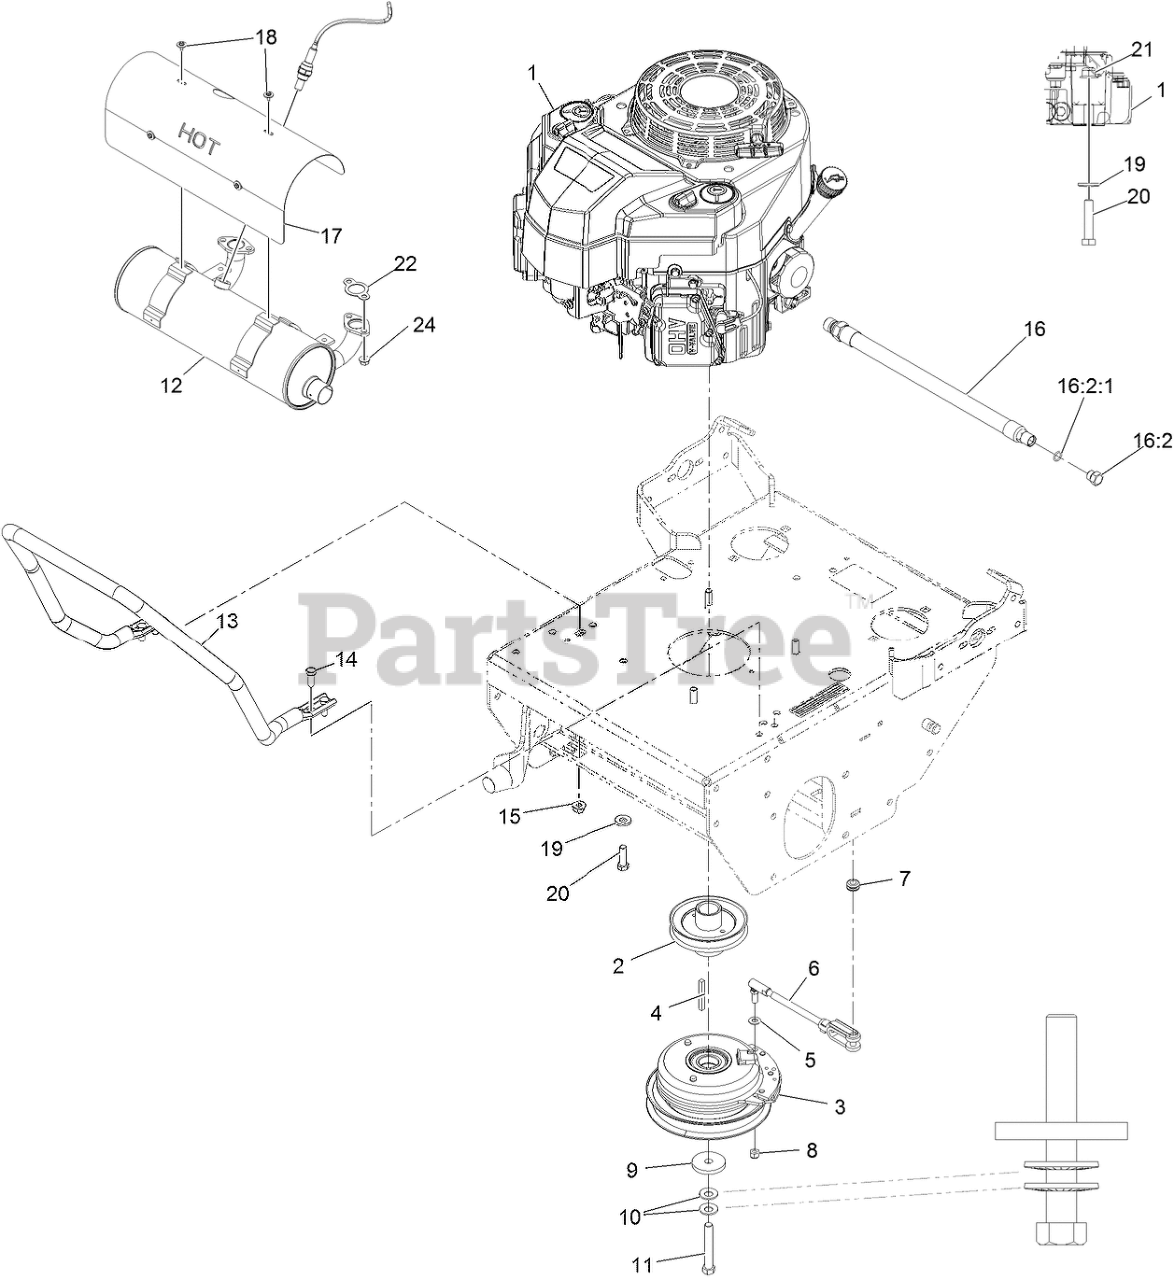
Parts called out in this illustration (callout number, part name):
2	SHEAVE, W/ HUB
3	CLUTCH, 125 FT/LBS, 1.13
4	KEY-SQUARE
5	WASHER-PLAIN
6	ASM, CLUTCH ANCHOR
7	GROMMET
8	NUT-LOCK
9	WASHER-CLUTCH
10	WASHER-SPRING
11	SCREW-HH
12	MUFFLER-TTX, EFI
13	Guard,Air Cleaner
14	SCREW-HH
15	NUT-HF, NI
16	OIL DRAIN HOSE ASM
16:2	PLUG-HH
16:2:1	O-RING
17	SHIELD-MUFFLER,TTX EFI
18	SCREW-HH, THREAD FORMING
19	WASHER-SPRING
20	SCREW-HH
21	NUT-HF, NI
22	GASKET-EXHAUST
24	NUT-FLANGE
